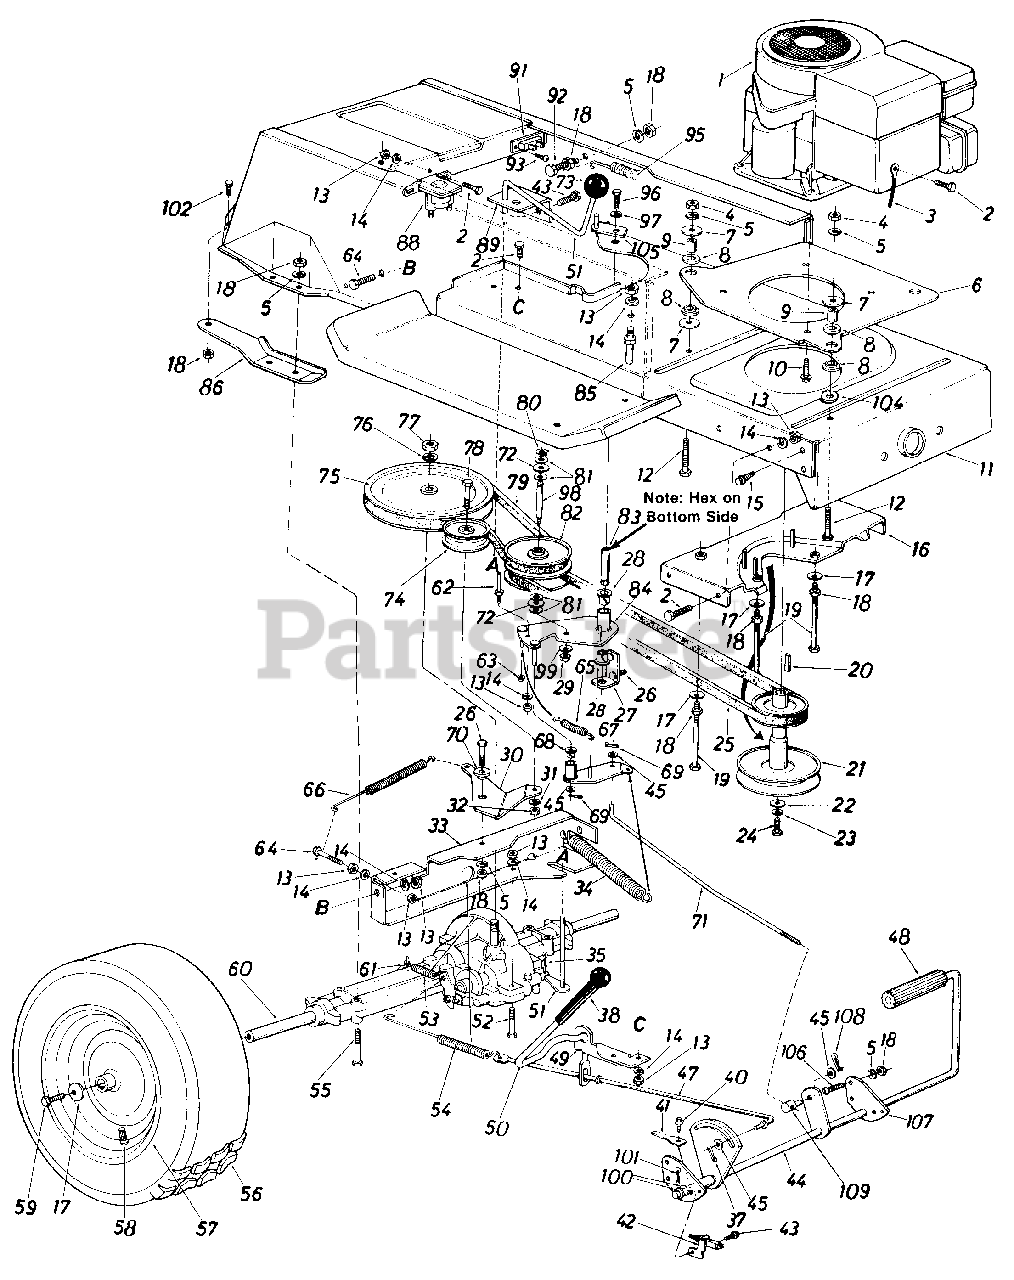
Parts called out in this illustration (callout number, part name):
1	Engine
2	Hex Bolt 1/4-20 x .62" Lg.*
3	Electric Ground Wire
4	Hex Nut 5/16-24 Thd.*
5	L-Wash. 5/16" I.D.*
6	Engine Mounting Plate
7	Fl-Wash. .320" I.D. x 1.25"
8	Engine Mounting Grommet
9	Spacer
10	Hex Bolt 3/8-16 x 1.25" Lg.
11	Lower Frame Ass'y.
12	Hex Bolt 5/16-24 x 1.25"*
13	Hex Nut 1/4-20 Thd.*
14	L-Wash. 1/4" I.D.*
15	Hex Wash. Hd. AB-Tap Scr. 5/16" x .75" Lg.
16	Belt Guard Brkt. Ass'y.
17	Bell-Wash. .345" I.D. x .88"
18	Hex Nut 5/16-18 Thd.*
19	Hex Bolt 5/16-18 x 4.00"*
20	Sq. Key 1/4" x 1/4" x 2.00"
21	Engine Pulley
22	Fl-Wash. 7/16" I.D. x 1.25"
23	L-Wash. 7/16" I.D.*
24	Hex Bolt 7/16-20 x 1.50" Lg.
25	Variable-Speed Belt .715 x 53" Lg.
26	Hex Bolt 5/16-18 x .50" Lg.*
27	Bearing Shaft Bracket
28	Flanged Nyliner Brg. 5/8" I.D. x .88" Lg.
29	Hex Nut 3/8-24 Thd.*
30	Idler Bracket
31	L-Wash. 3/8" I.D.*
32	Hex Nut 3/8-24 Thd.*
33	Transaxle Support Brkt.
34	Ext. Spring .94" O.D. x 6.7
35	Cotter Pin 1/8" Dia. x 1.0"*
37	Cotter Pin 3/32" Dia. x 1.0"*
38	Grip Black
40	Hex Wash. Hd. Self-Tap Scr. 1/4-20 x .50" Lg.
41	Switch Actuator
42	Safety Switch
43	Hex Wash. Hd. AB-Tap Scr. 1/4 x.62" Lg.
44	Clutch & Brake Pedal Ass'y.
45	Fl-Wash.
47	Brake Rod
48	Foot Pad
49	Brake Lever Bracket
50	Hill Holder Brake Handle
51	Shift Lever Ass'y.
52	Hex Bolt 1/4-28 x 1.75" Lg.*
53	Ext. Spring .38" O.D. x 2.5"
54	Ext. Spring .59" O.D. x 7.08"
55	Hex Bolt 5/16-18 x 2.50"*
56	Wheel Ass'y. Comp. (688)
57	Wheel Rim Only(688)
58	Air Valve
59	Hex Bolt 5116-24 x .75" Lg.*
60	Transaxle Complete
61	Brake Return Spring Anchor
62	Belt Guard Pin 1/4-20 Thd.
63	Cap Speed Nut 1/4" Dia.
64	Hex Bolt 1/4-20 x .62" Lg. Grade 5
65	Ext. Spring .50" Dia.
66	Ext. Spring .56" O.D. x 5.96"
67	Variable Speed Torque Brkt. Ass'y
68	Flanged Bearing
69	Cotter Pin 3/32" Dia.*
70	Shoulder Spacer .500" Dia .27" Lg.
71	Speed Control Link
72	Truss Bearing .56 Dia. x 1 .25 "
73	Ball Knob
74	Fl-Idler Pulley 3.25" x 1.0"
75	1/2" "V"-Pulley 8.0" O.D. x .50" I.D.
76	L-Wash. 1/2" I.D.
77	Hex Jam Nut 1/2-20 Thd.*
78	Hex Bolt 3/8-24 x 1.50" Lg.*
79	Variable Sp. Belt .715 x 44"
80	Snap Ring .56" Dia.
81	Fl-Wash .
82	Variable Sp. Pulley Ass'y.
83	Bearing Shaft
84	Variable Speed Brkt. Ass'y.
85	Belt Guard Pin 1/4" Dia. x 1.68 " Lg. .
86	Transaxle Support Brkt. R. H .
86	Transaxle Support Brkt. L.H.
88	Solenoid
89	Shift Lever Bracket
91	Circuit Breaker
92	Hex Bolt 5/16-18 x 1.25" Lg.
93	Truss Hd. Phil. Scr. #10 x 1/2 " Lg.
95	Ext. Spring .99" O.D. x 11.0"
96	Hex Bolt 3/8-24 x .75" Lg.*
97	Bell-Wash. .38" I.D. x .88"
98	Shaft .56" Dia. x 3.875" Lg.
99	Bell-Wash. .39" I.D. x 1.12"
100	Fl-Wash.
101	Cotter Pin
102	Hex Wash. Hd. Scr. 5/16-18 x .62" Lg.
104	Fl-Wash. .32" I.D. x 1.25"
105	Belt Guard
106	Truss Mach. Scr. 5/16-18 x .75" Lg.*
107	Pedal Bracket
108	Hairpin Cotter 1/8" Dia.
109	Ferrule
